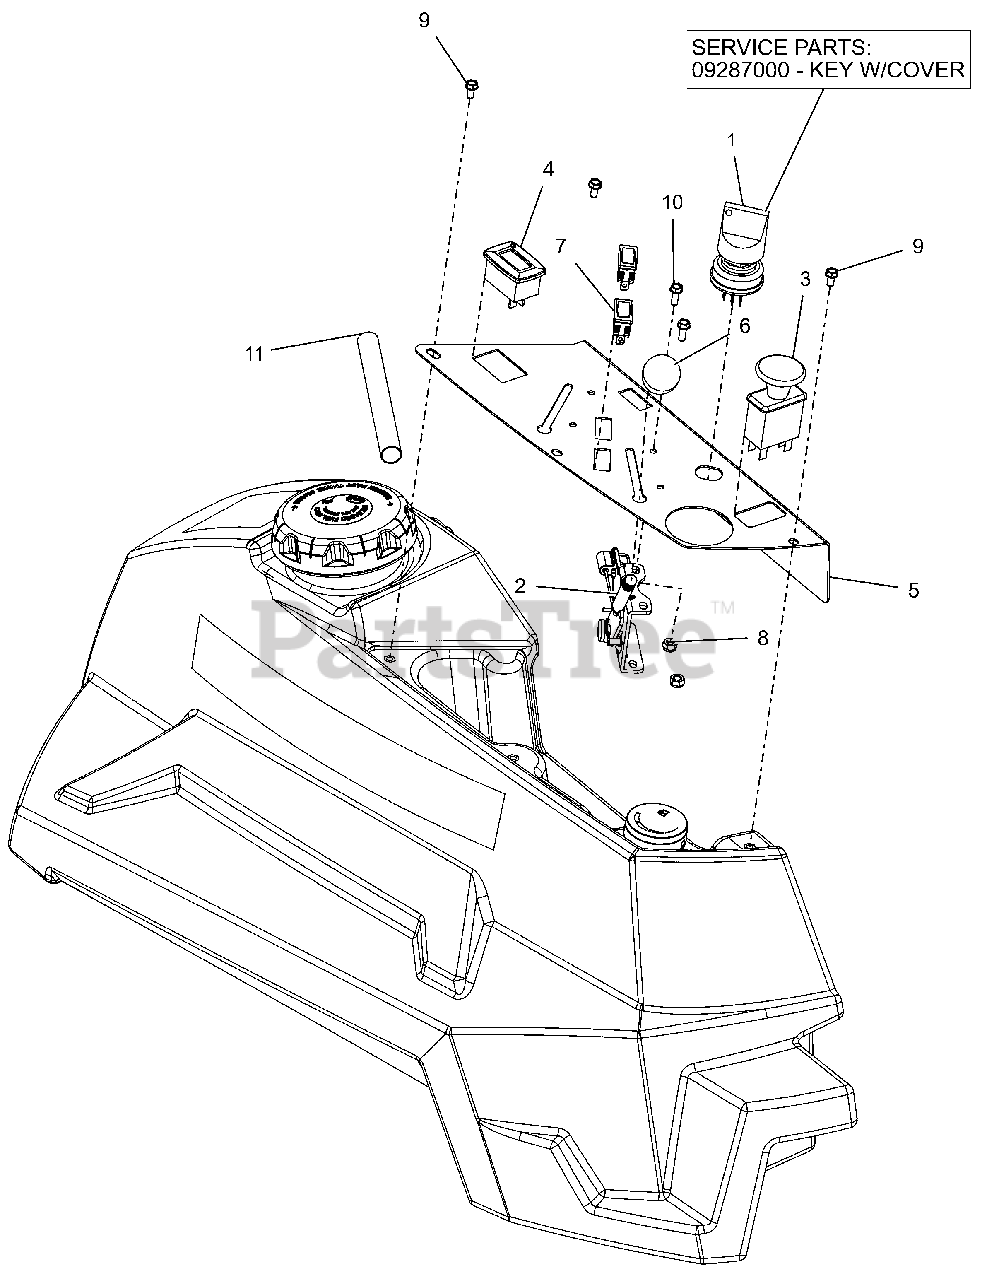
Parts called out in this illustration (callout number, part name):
1	SWITCH, IGNITION
1	KEY, W/ SHIELD
2	CABLE, PRO-CTRL 35.50"
3	SWITCH, CLUTCH
4	METER, HOUR W/MAINTENANCE
5	PT400 CONTROL PANEL - RED
6	KNOB-CONTROL-BLACK .38-16X.50
7	LIGHT,INDICATOR
8	@NUT-LK-NYL 10-24 W/INSRT YWZC
9	SCR-MCH 10-24X.38 HWHSTAINLESS
10	@SCR-MCH 10-24X.50 HWH YWZC
11	SLEEVE, THERMAL 6"
